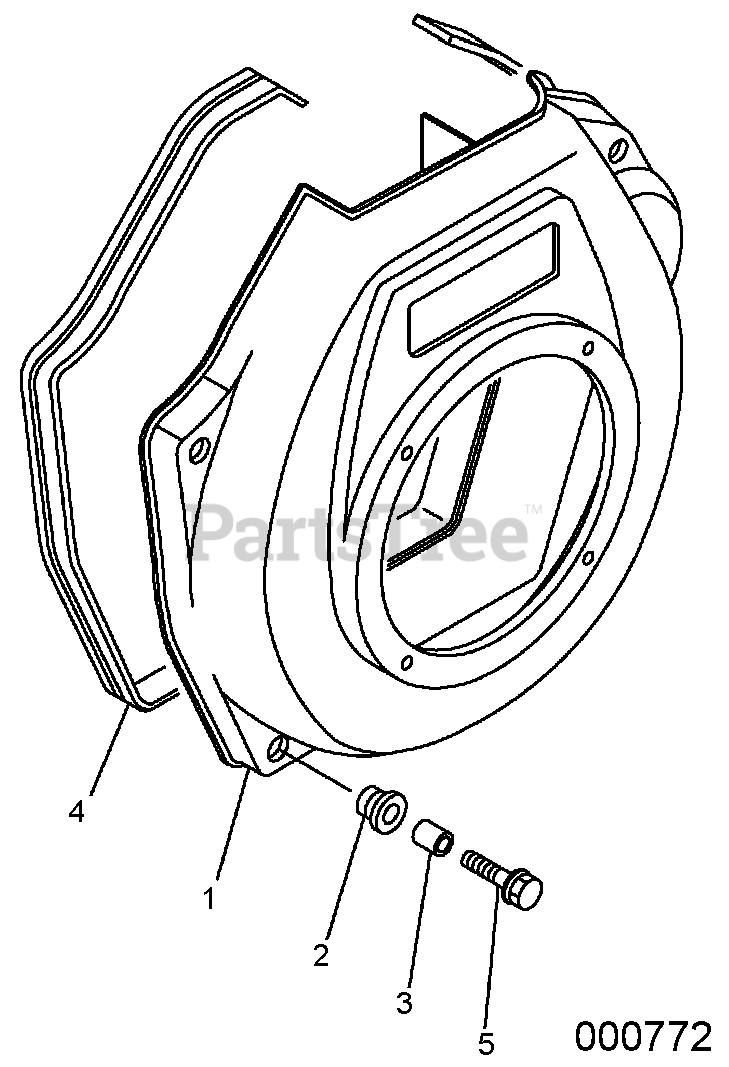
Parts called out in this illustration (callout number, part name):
1	COOLING FAN CASE
2	RUBBER CUSHION
4	FAN CASE SEAL
5	FAN CASE BOLT
